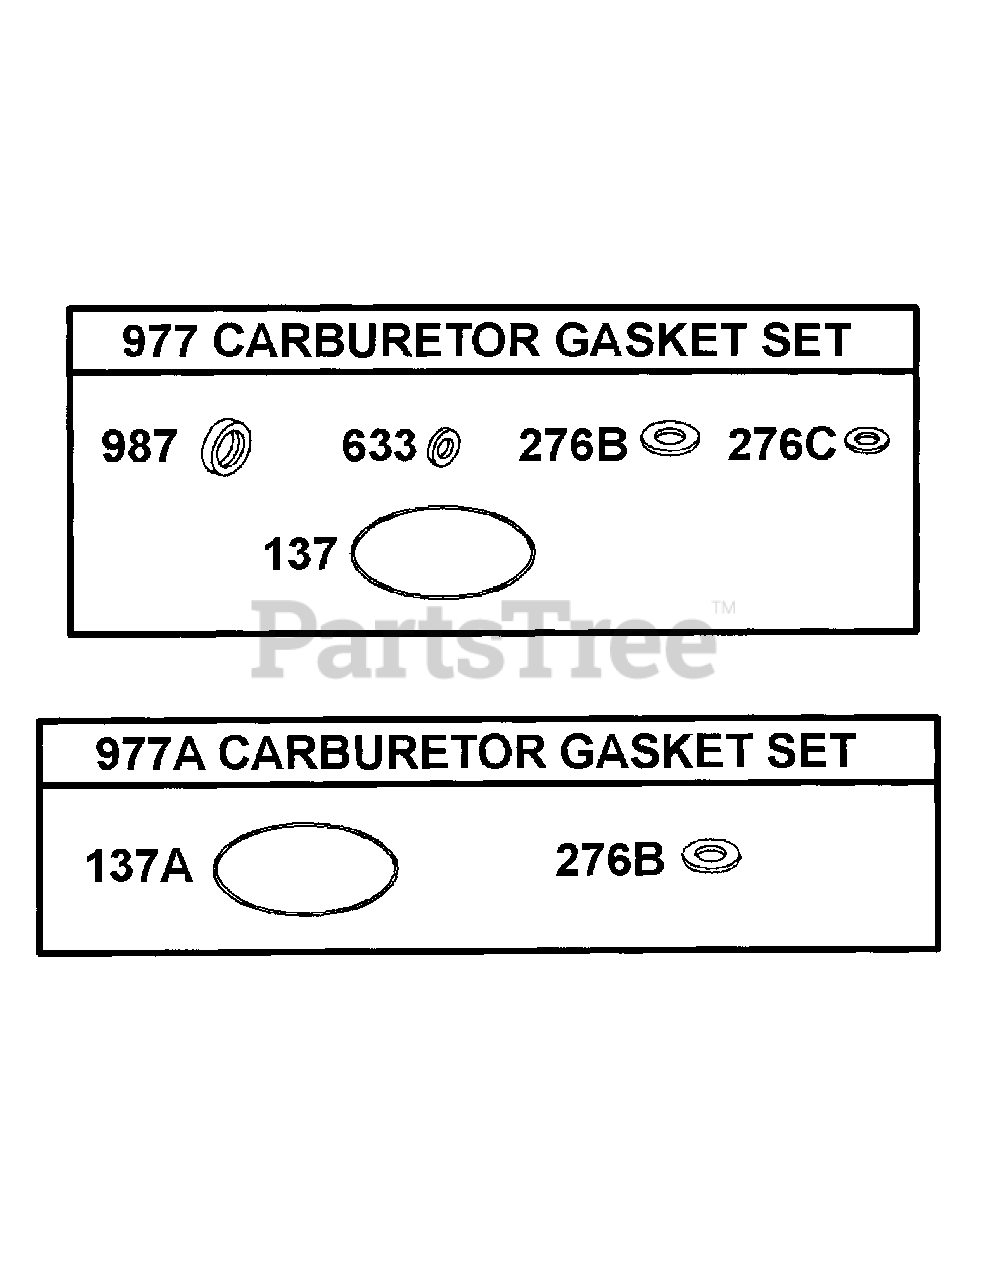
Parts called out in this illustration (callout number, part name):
137	Gasket-Float Bowl
276B	Washer-Sealing (Float Bowl)
276C	Washer-Sealing (Carburetor Plug)
633	Seal-Choke/throttle Shaft
977	Gasket Set-Carburetor
977A	Gasket Set-Carburetor
987	Seal-Throttle Shaft
